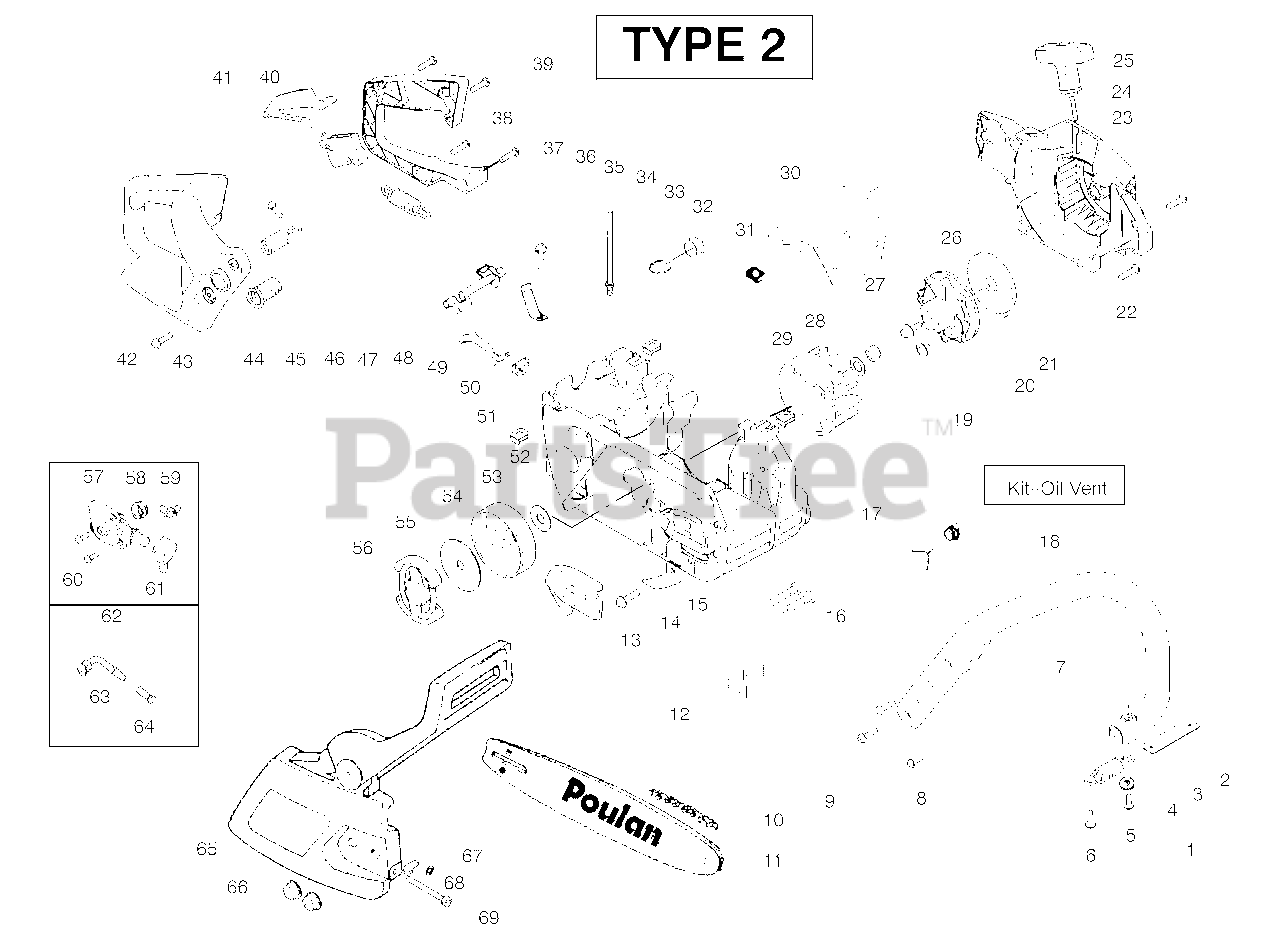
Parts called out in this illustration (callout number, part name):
1	Assy.-Isolator
2	Limiter Strap
3	Spring-Isolator
4	Washer
7	Front Handle
10	Chain -18"
11	Bar - 18"
13	Plate-Bar Mount.
15	Chain Catcher
16	Bolt-Bar
17	Assy-Oil Cap
18	Kit-Oil Vent
19	Nut-Flywheel
21	Starter Pulley
23	Housing-Fan
24	Kit - Rope
25	Handle-Starter
26	Spring-Recoil
28	Washer-Flywheel
29	Assy-Flywheel
30	Shield - Heat
31	Clip - "U"
32	Assy-Fuel Cap
33	Fitting-fuel line
34	Kit-Fuel line
35	Spring-Switch
37	Cover-Rear Handle
40	Throttle Lockout
41	Trigger-Throttle
42	Handle - Rear
43	Screw
44	Assy Isolator-lower
45	Kit-Isolator
47	Spring-Isolator
48	Lever-Switch
49	Lever-Choke
50	Grommet-Knob
51	Nut-"U"-Type
52	Kit-Chassis Assy.
53	Washer-Thrust
54	Assy.-Clutch Drum w/bearing
55	Washer-Clutch
56	Assy. Clutch
57	Kit - Oil Pump
58	Gear-Worm Spring
59	Elbow-Oil Pickup
61	Seal Block
62	Assy-Oil Pick-up
63	Pick-up Oiler
64	Filter-Oil
65	Assy.-Chain Brake
66	Nut-Bar Mounting
67	Pin-Bar Adjust
68	Retainer
69	Kit-Bar Adjusting
